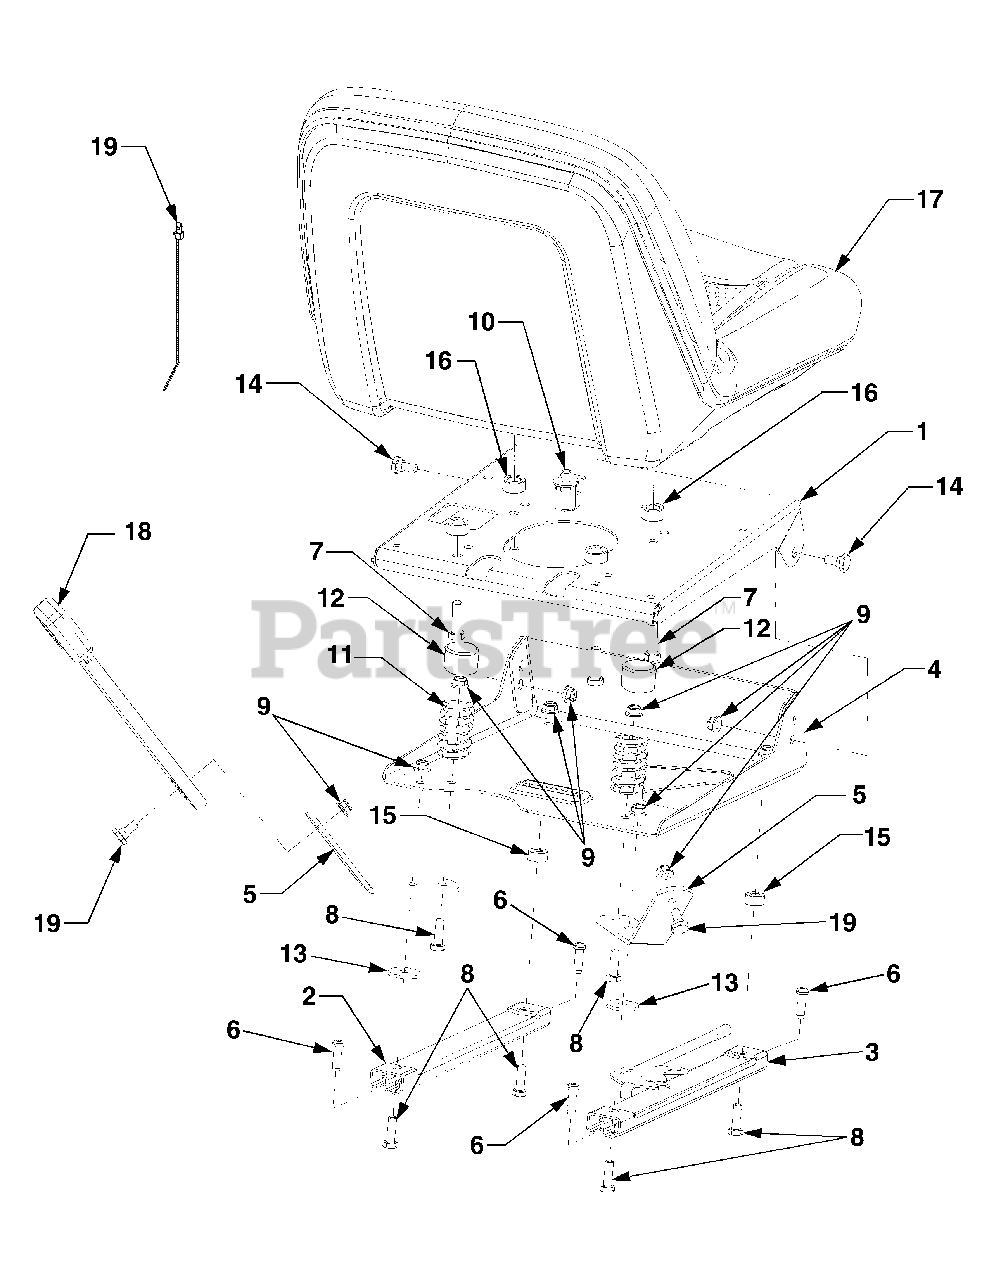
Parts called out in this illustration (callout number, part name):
3	Track, Seat - w/Latch
7	Screw, Hex Cap, 3/8-16 x 1.25 GR5
8	Screw, Hex Cap, 5/16-18 x 1.0 GR5 (Replaces 710-3038)
9	Nut, Hx Insert Flnge Lk, 5/16-18
10	Switch, Seat, N/O
11	Spring, Compression
12	Cap, Spring
13	Washer, Flat, .33 x 1.25 x .12
14	Screw, Shoulder, .435 x .178:5/16-18
15	Spacer, .315 x .75 x .375
16	Spacer, .505 x .88 x .44
17	Seat, High Back
18	Belt Assembly, Seat
19	Tie, Push Mnt. Cable
19	Screw, Shoulder, .435 x .178-5/16-18
